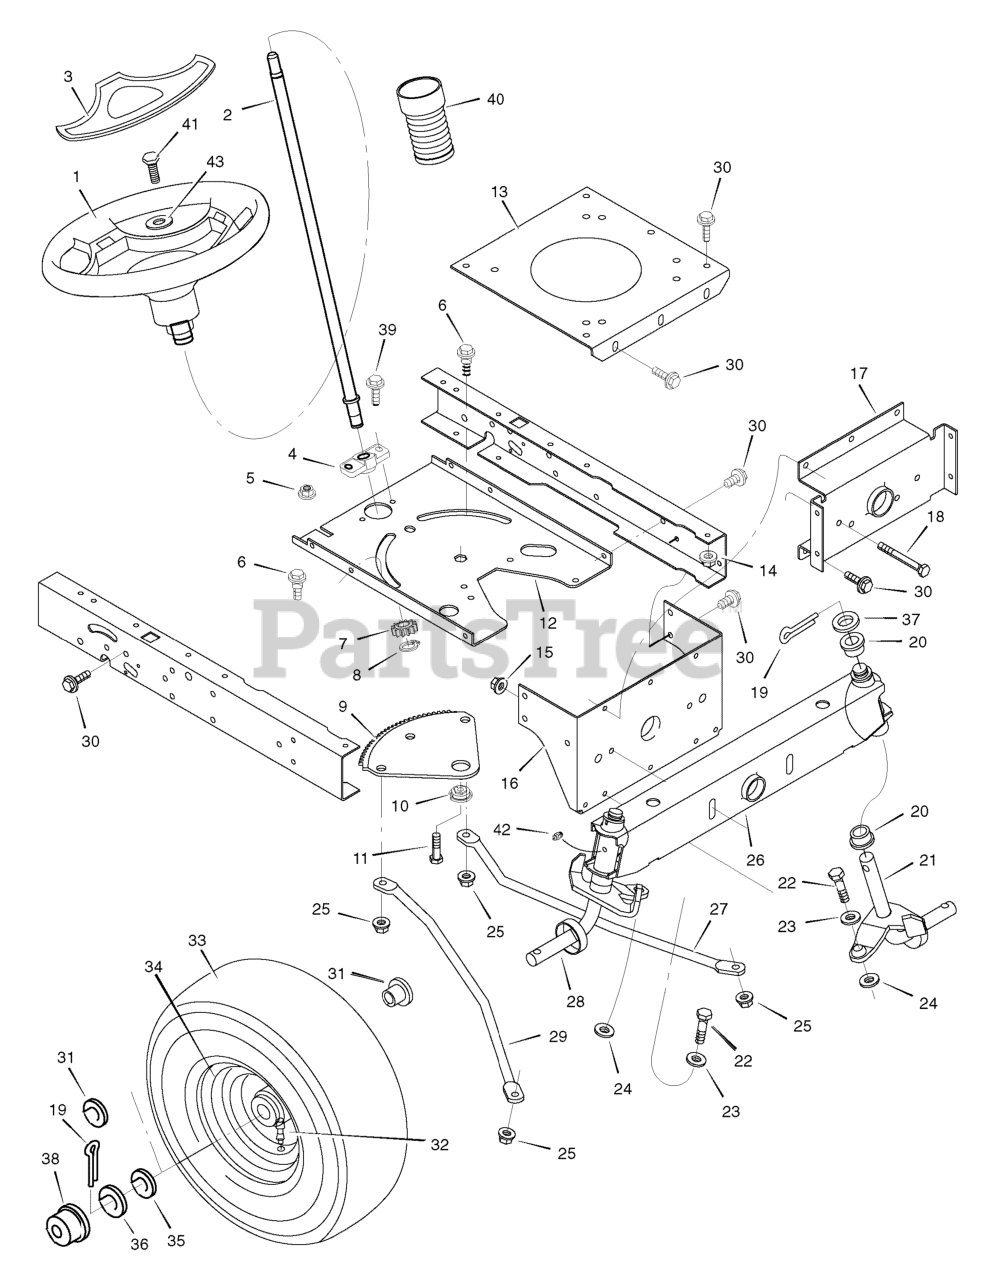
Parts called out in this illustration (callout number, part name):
1	Wheel, Steering
2	Post, Steering
3	Cover, Steering Wheel
4	Bearing
5	Nut, Flange
6	Bolt, Shoulder
7	Gear, Pinion
8	Ring, Snap
9	Gear, Sector
10	Bearing
11	CAPSCREW, Hex Head, 5/16-18 x 1
12	Plate, Steering
13	Plate, Engine
14	Nut, Flange
15	Nut, Flange
16	Bracket, Hanger
17	Axle, Hanger
19	Pin, Cotter
20	Bearing
21	Spindle Assembly, Left
22	Bolt
23	Washer
24	Washer
25	Nut, Flange
26	Axle Assembly
27	Drag Link, Left
28	Spindle Assembly, Right
29	Drag Link, Right
31	Bearing, Wheel
32	Stem, Valve
34	Wheel andTire Assembly
38	Hub Cap
40	Bellows
41	Screw, Hex
42	Fitting, Grease
43	Washer
